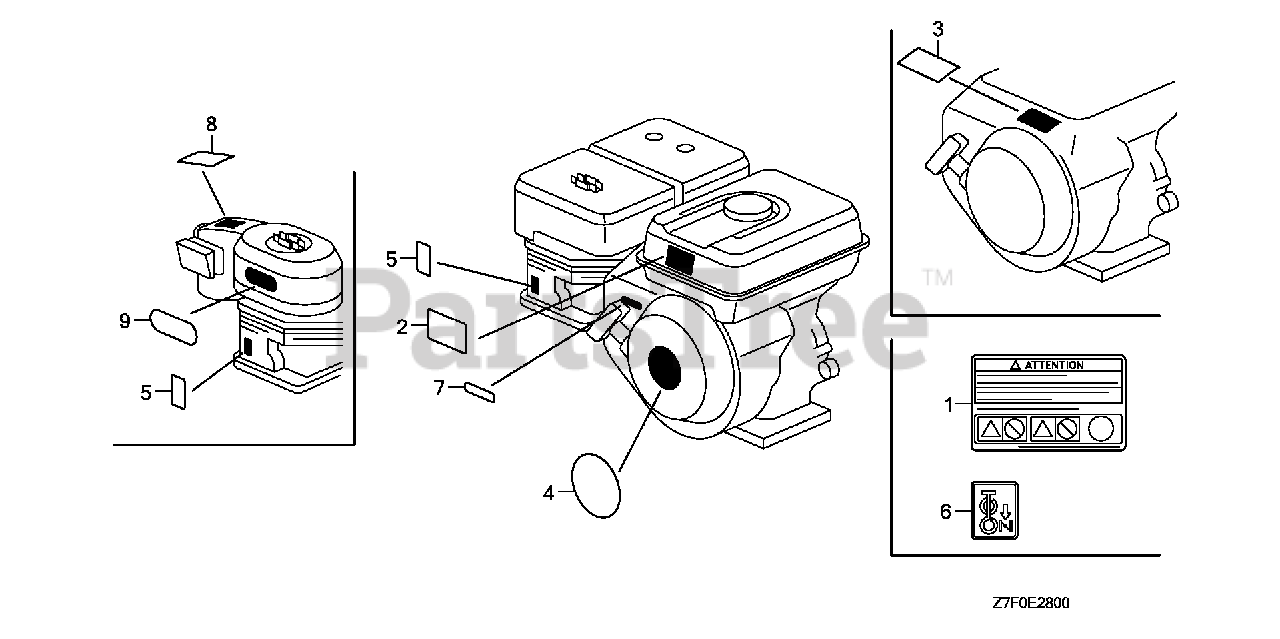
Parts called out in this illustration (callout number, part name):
1	MARK, OPERATOR CAUTION (FRENCH)
2	MARK, OPERATOR CAUTION (ENGLISH)
2	MARK, OPERATOR CAUTION (PICTOGRAPH)
4	EMBLEM (GX390) (HONDA)
5	MARK, CHOKE
7	MARK, THROTTLE INDICATION
